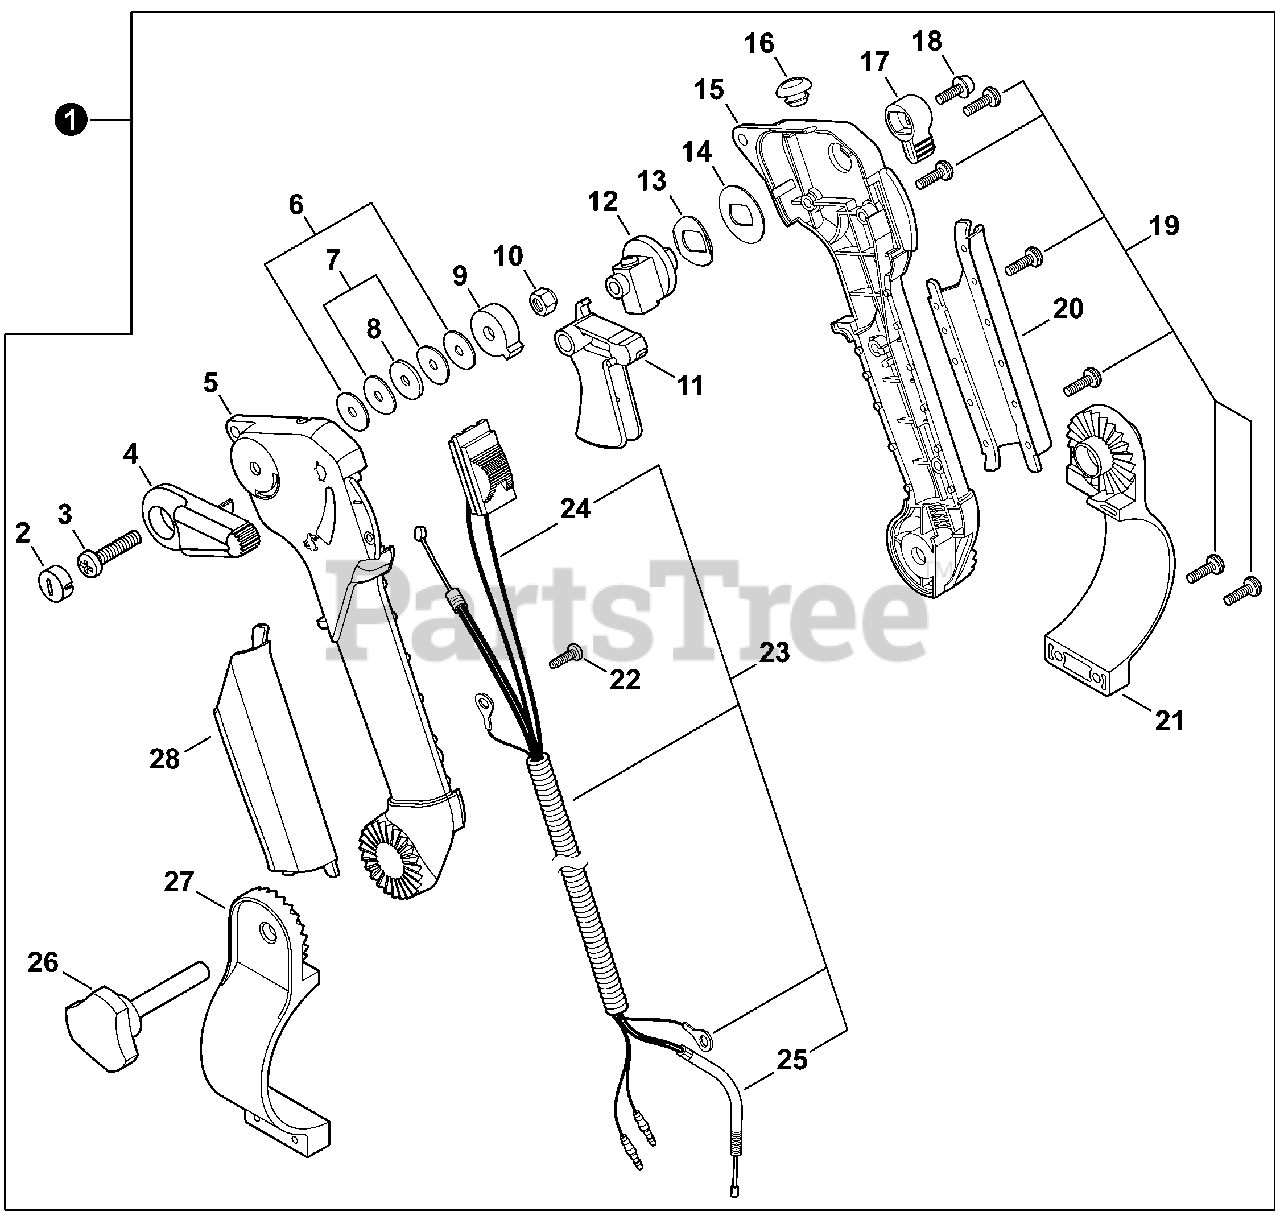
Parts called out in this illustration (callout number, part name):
1	THROTTLE CONTROL ASSY
2	CAP, BOLT
3	BOLT M6×25
4	CONTROL, THROTTLE
5	CONTROL HANDLE - LEFT
6	WASHER M6
7	WASHER, SPRING
8	WASHER M6
9	LEVER, THROTTLE
10	NUT, NYLON M6
11	TRIGGER, THROTTLE
12	LIMITER ASSY, THROTTLE
13	WASHER, WAVE
15	CONTROL HANDLE - RIGHT
16	PLUG, THROTTLE LIMITER
17	LEVER, THROTTLE LIMITER
18	SCREW M4×16
19	SCREW M4×16
20	GRIP, RIGHT
21	BRACKET, RIGHT
22	SCREW M3×8
23	CABLE ASSY, CONTROL
24	SWITCH, ON-OFF
25	CABLE, THROTTLE
26	KNOB, SCREW
27	BRACKET, LEFT
28	GRIP, LEFT
